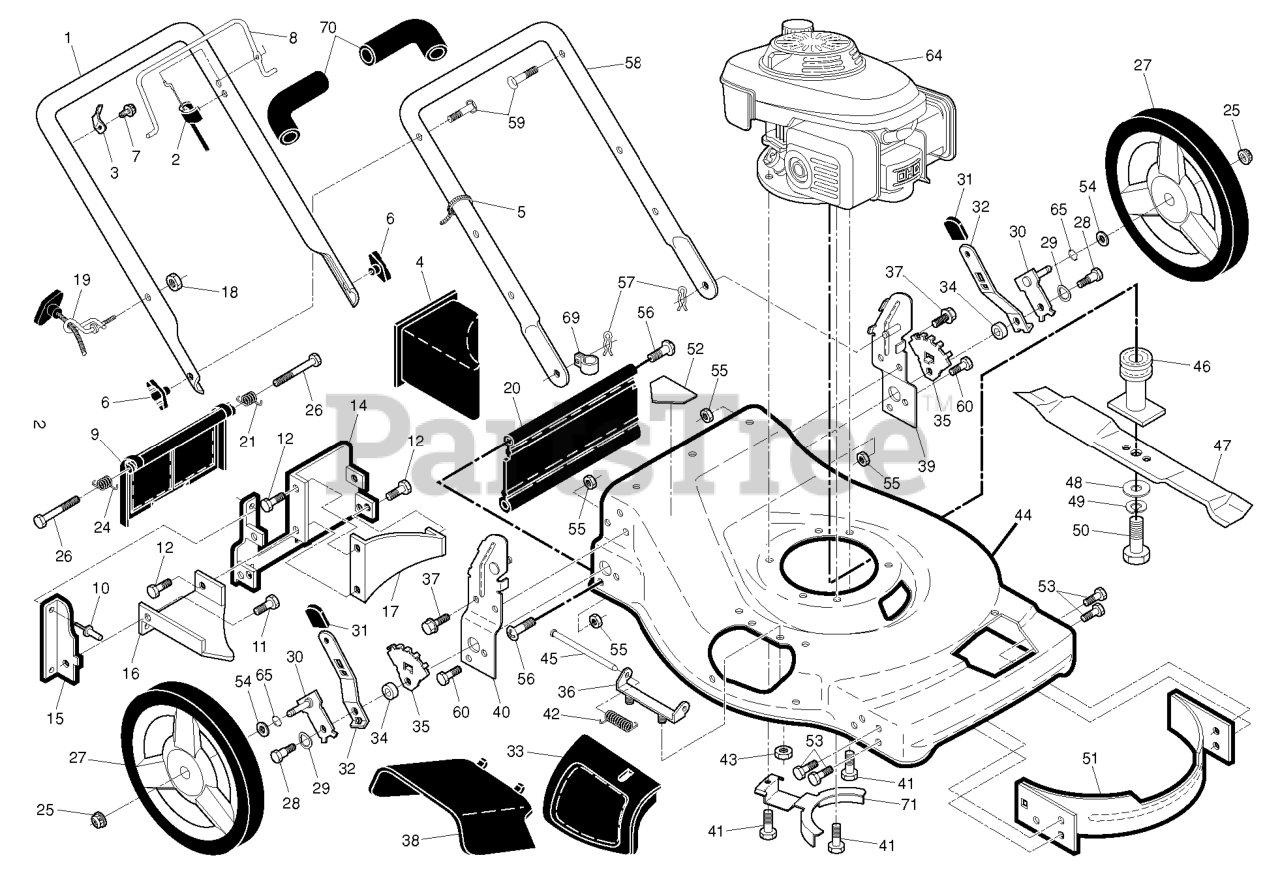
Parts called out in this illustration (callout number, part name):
1	HANDLE.ASM.GRY.W/GRIP
2	CABLE.ASM.ZONE.CONTROL
3	BRACKET UPSTOP
4	PLUG.MULCH.22RD
5	TIE GUIDE
6	KNOB, DEFLECTOR
8	BAIL.MZR.EZ2.22 PLUS.ORANGE
9	REAR DOOR ASSY
10	RIVET BLIND
11	SCREW.HXTAP.10-24
12	SCREW 14-20 X 5/8
14	PLATE.BACK
15	SIDE BAFFLE
16	DISCHARGE BAFFLE
17	REAR BAFFLE
18	NUT
19	RB GUIDE.ROPE.STD.BLK.ZIN WSL
20	SKIRT.REAR.22RD/SD.FO/VE
21	SPRING.LH.22.REAR.DOOR.EZ.EMPT
24	SPRING.RH.22.REAR.DOOR.EZ.
25	NUT.HEX.FLANGE.3/8-16.LOCKNUT
27	WHEEL ASSY
28	BOLT SHOULDER 3/8 -16X1
29	WASHER.CURVED.CYLINDRICAL
30	ARM.ASM.AXLE.5/9.POS.BZP
31	SELECTOR KNOB
32	SELECTOR SPRING
33	DOOR.MULCH.22.REAR.FWGD.GREY
34	SPACER.HEIGHT.ADJUSTER
35	WHEEL ADJ BRACKET
36	BRACKET.ASM.HINGE.21.FWGD.
37	BOLT.HEX.HD.WASHER.5/16-18X.75
38	DEFLECTOR.CLIPPING.22.FGD
39	BRACKET.ASM.HDL.LT.EZEM.22.ORG
40	BRACKET.ASM.HDL.RT.EZEM.22.ORG
41	BOLT 3/8-16X1-1/8
42	SPRING.TORSION
43	LOCKNUT.NYLOC.1/4-20
44	HOUSING.22.TOR.FWD.ORANGE.E/FR
45	ROD.HINGE.21
46	RP ADAPTER.BLADE.25MM.21F
47	BLADE.22.MULCH.STANDARD
48	WASHER,HARDEN
49	LOCKWASHER
50	SCREW, HEX HD 3/8-24 X 1-3/8
51	FRONT BAFFLE KIT
52	DANGER DECAL
53	SCREW 1/4X20
54	WASHER.FLAT.1/2
55	LOCKNUT
56	HINGE SCREW
57	HAIRPIN COTTER
58	HANDLE.LOWER.21.NB.GREY
59	BOLT, HANDLE 5/16-18X1.75
65	O-RING..070X.487.NEOPRENE
69	CLIP.CABLE.BLK
70	GRIP.HANDLE.FOAM.WIDE.(1 SIDE)
71	BRACKET.ENG/BELTKEEPER
